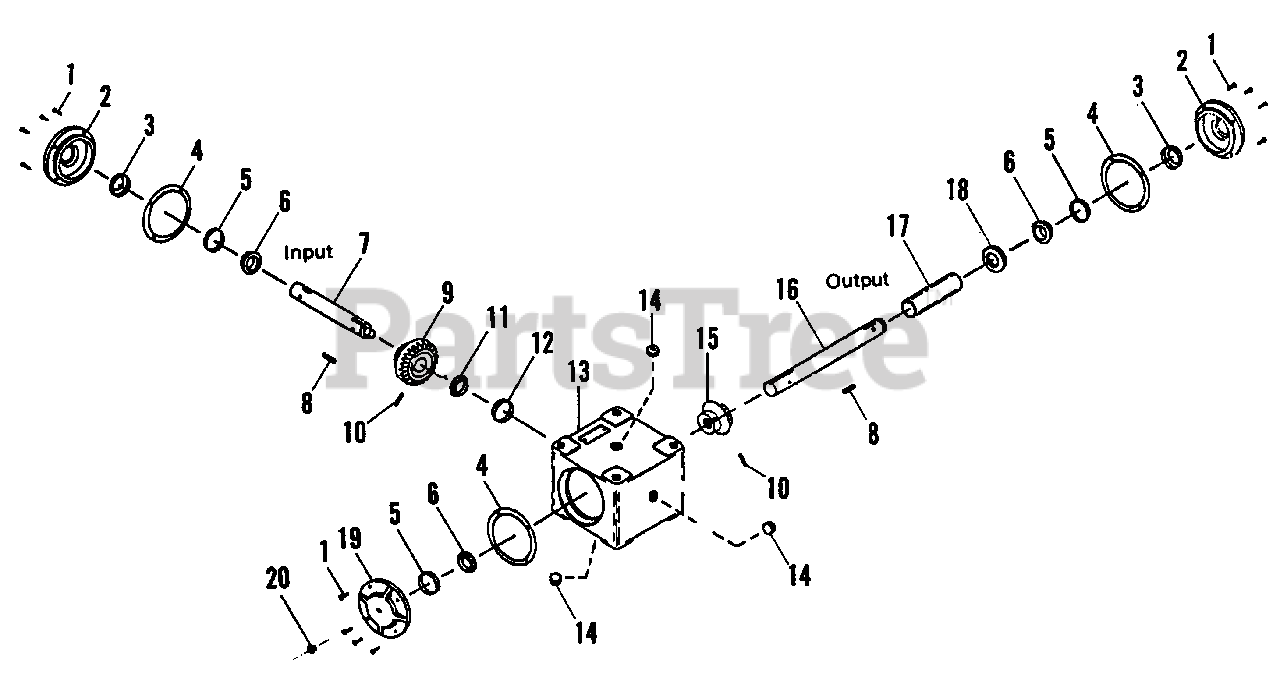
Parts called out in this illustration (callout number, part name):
1	SCREW, Hex Whizloc Flange, 5/16 x 3/4
2	CAP, Housing
3	SEAL, Shaft, 1 x 1-1/2 x 5/16
4	GASKET, .015
4	GASKET, .005
4	GASKET, .003
5	BEARING CUP
6	BEARING, Cone
7	SHAFT, Pinion
8	KEY, 1/4 x 1/4 x 7/8
9	GEAR, Bevel
10	ROLL PIN, 5/16 x 2
11	BEARING, Cone
12	BEARING CUP
14	PLUG, Sq. Hd., Solid 1/4 NPT
15	GEAR, Pinion
16	SHAFT, Output
19	CAP, Housing
20	PLUG, Vent, 1/8-27
